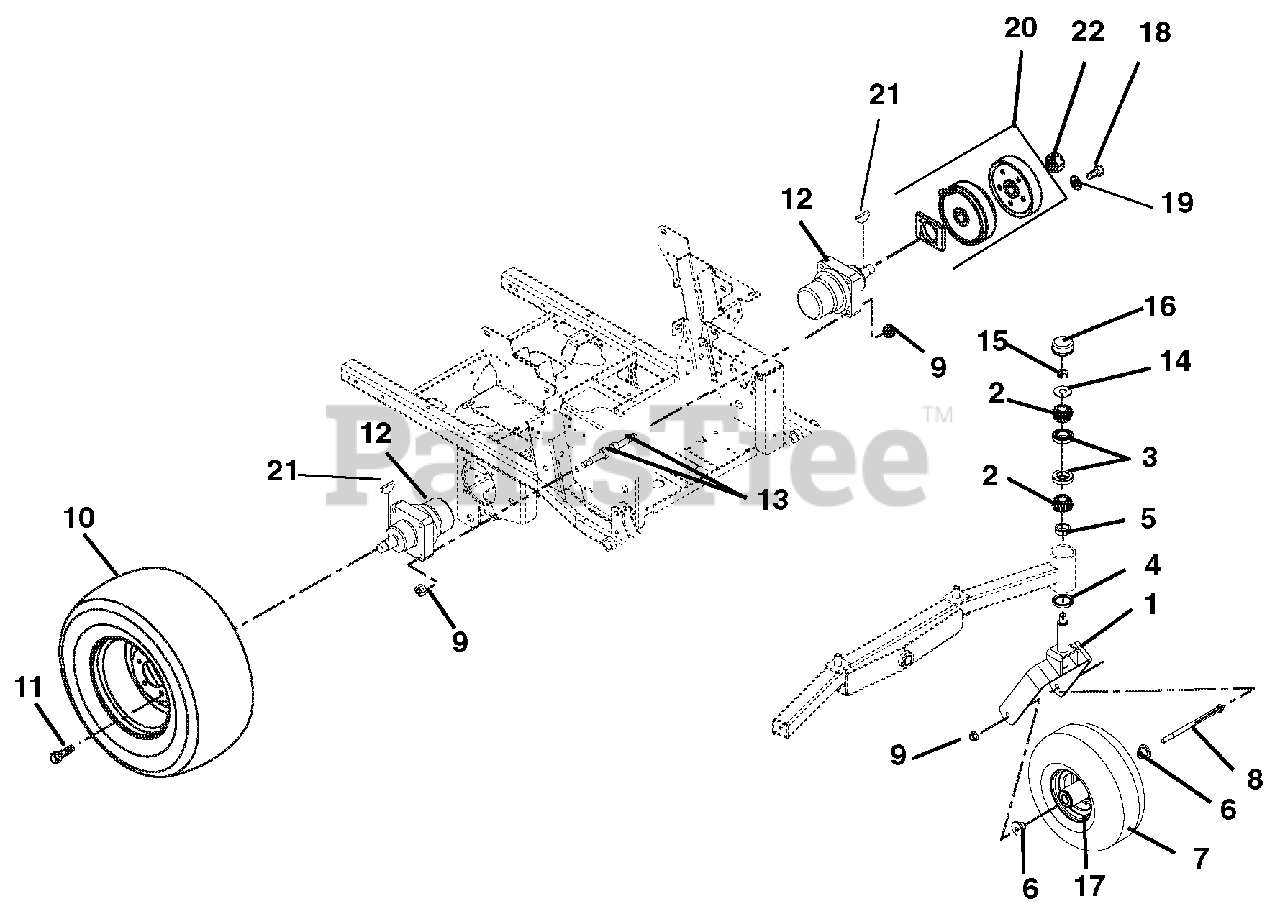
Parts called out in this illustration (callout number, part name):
1	Fork, Front
2	Bearing, Cone
3	Bearing, Cup 2.328 x .465
4	Bearing Seal 1.75 x 2.332 x .312
5	Spacer, 1.258ID x 1.750OD x .550
6	Spacer, Wheel
7	Wheel/Tire Assembly
8	Bolt, Hex .50-13 x 9.00 Grade 5
9	Nut-Locking-Top-Flange .50-13
10	Tire/Wheel Assembly, 24 x 11.50-12
11	Bolt, Lug .50-20 x 1.38
12	Wheel Motor, 18E (CCW)
13	Bolt, Hex .50-13 x 2.75 Grade 8
14	Washer, Flat Steel, .812 x 2.00 x .148
15	Nut, Jam Center-Lock .75-16
16	Cap, Dust
17	Bearing, 25mm I.D. x 52mm OD x 15mm
18	Bolt, Hex .31-18 x 1.50 Grade 8 EP30
19	Waher, Lock .31 x .078
20	Kit, Parking Brake Service
21	Key, Woodruff .31 x 1.00
22	Nut, Locking-Jam-Patch 1.00-20
